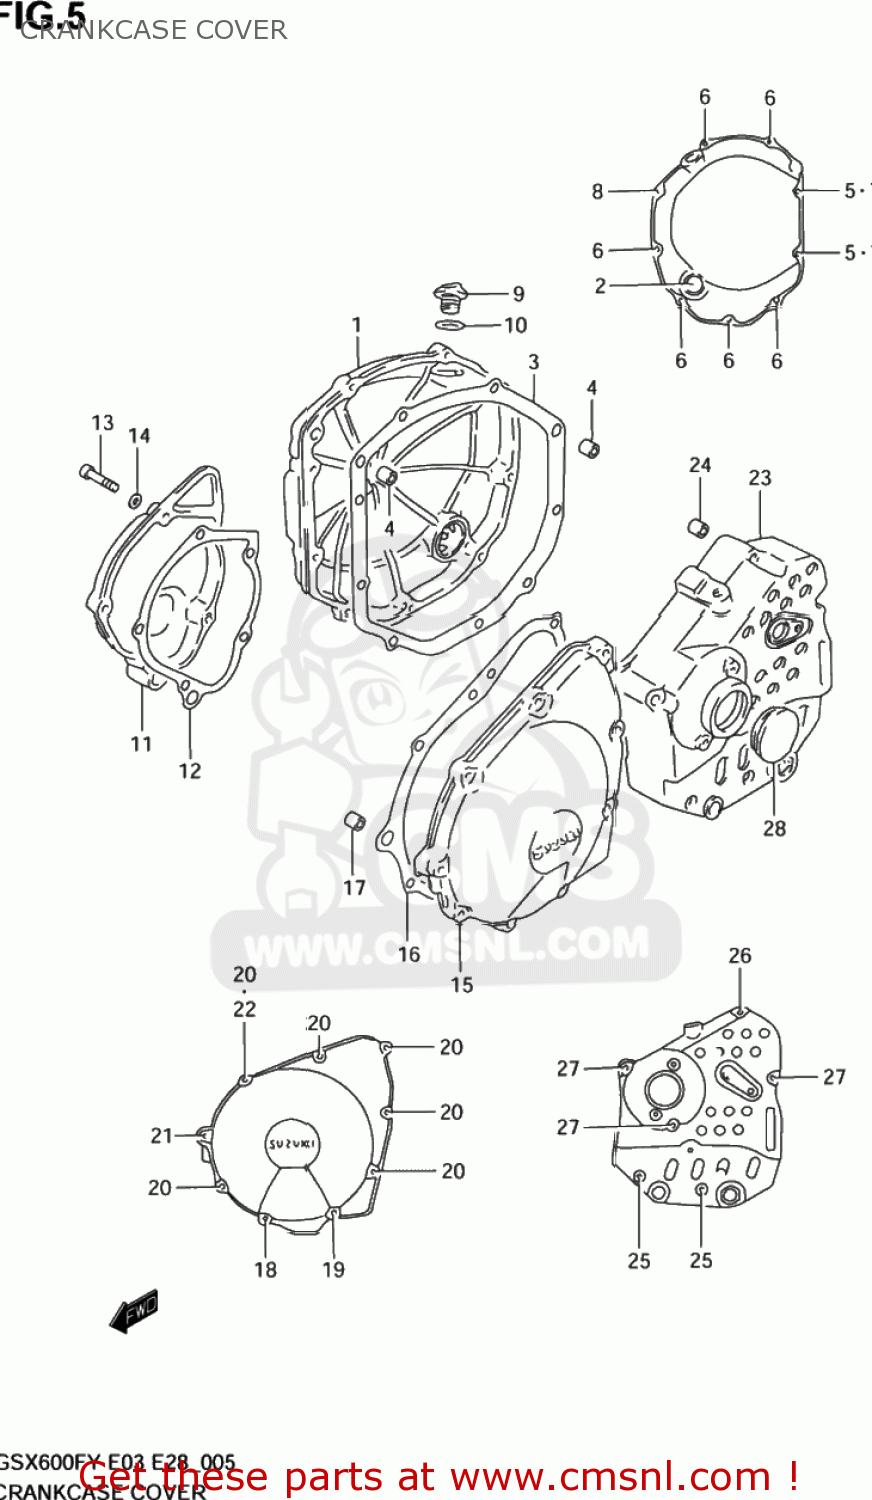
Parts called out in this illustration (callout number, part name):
1	COVER,CLUTCH
2	LENS,OIL LEVEL CHECK
3	GASKET,CL COVER (NAS)
4	PIN
5	GASKET(5.8X11X1.2) (NAS)
6	BOLT,CL.COVER
7	BOLT
8	BOLT
9	PLUG
10	O RING(D:3.1,ID:16.8)
11	COVER,SIGNAL GENERATOR
12	GASKET,SIGNAL GEN COVER (NAS)
13	BOLT(6X22)
14	GASKET(5.8X11X1.2) (NAS)
15	COVER,STARTER GEAR
16	GASKET,STARTER GEAR COVER (NAS)
17	PIN(8.4X11X20)
18	BOLT,OIL FILLE
19	BOLT,CRKCASE,R
20	BOLT,CL.COVER
21	BOLT
22	GASKET(5.8X11X1.2) (NAS)
23	COVER,ENGINE SPROCKET
24	PIN
25	BOLT
26	BOLT
27	BOLT
28	CAP(OD:36)
